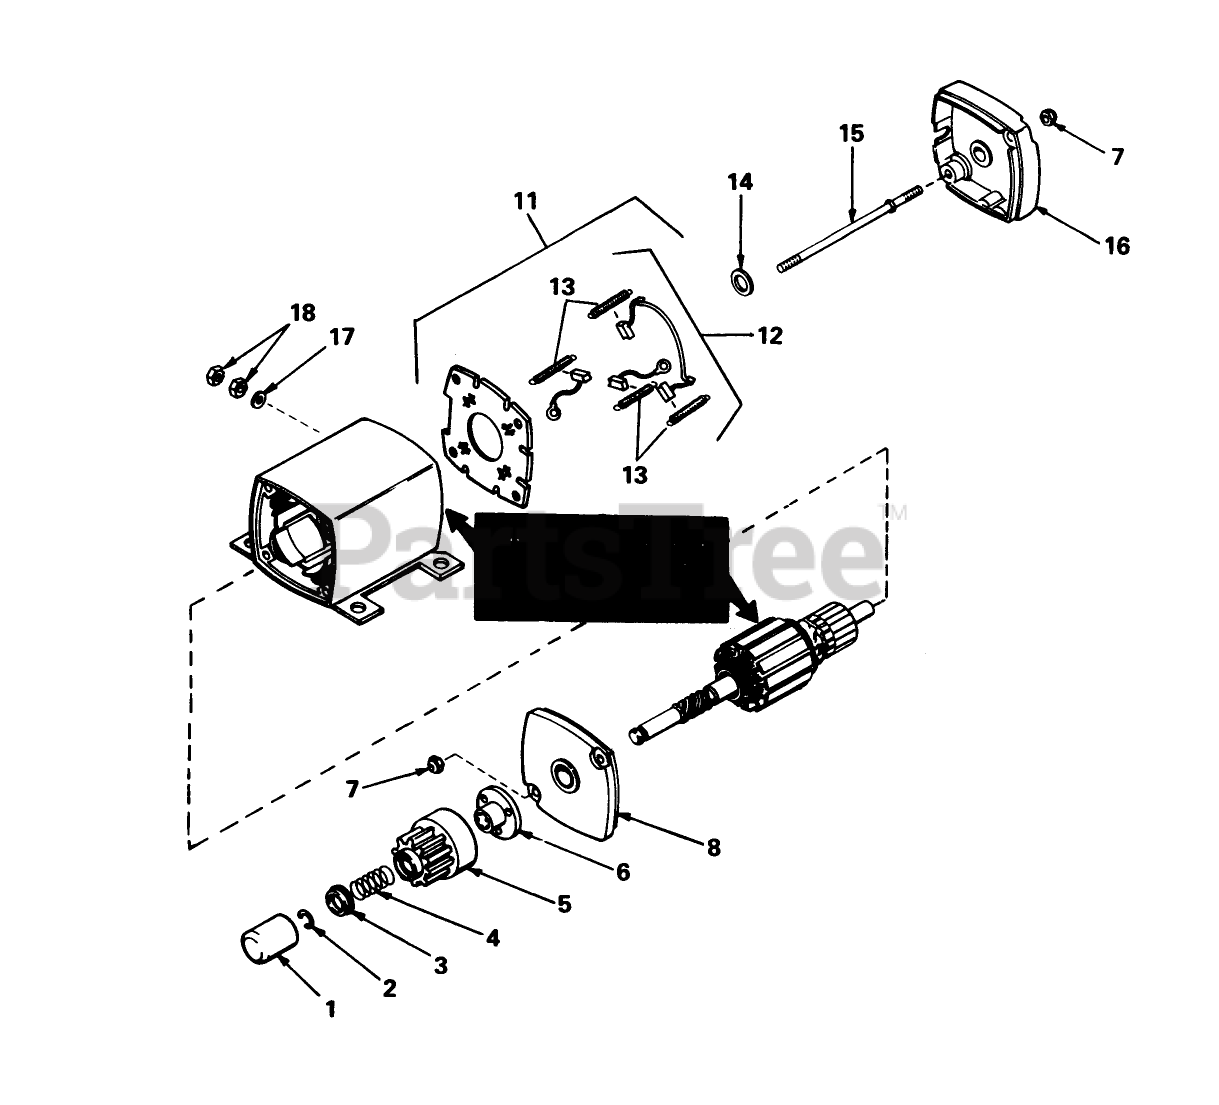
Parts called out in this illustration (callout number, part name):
1	Cover-Dust
2	Ring-Retainer
3	Retainer-Spring
4	Spring-Anti Drift
5	Gear
6	Nut-Engaging
7	Nut-Lock
8	Cap Assy., Drive End
11	Card Assy., Brush (Incl. No. 12)
12	Brush Spring Kit (Incl. 4 pcs. of #13)
13	1545D SUP TO W/3256
14	Washer-Thrust
15	Bolt
16	2035A67 WIZARD W/34
17	Washer
18	Nut-Hex
